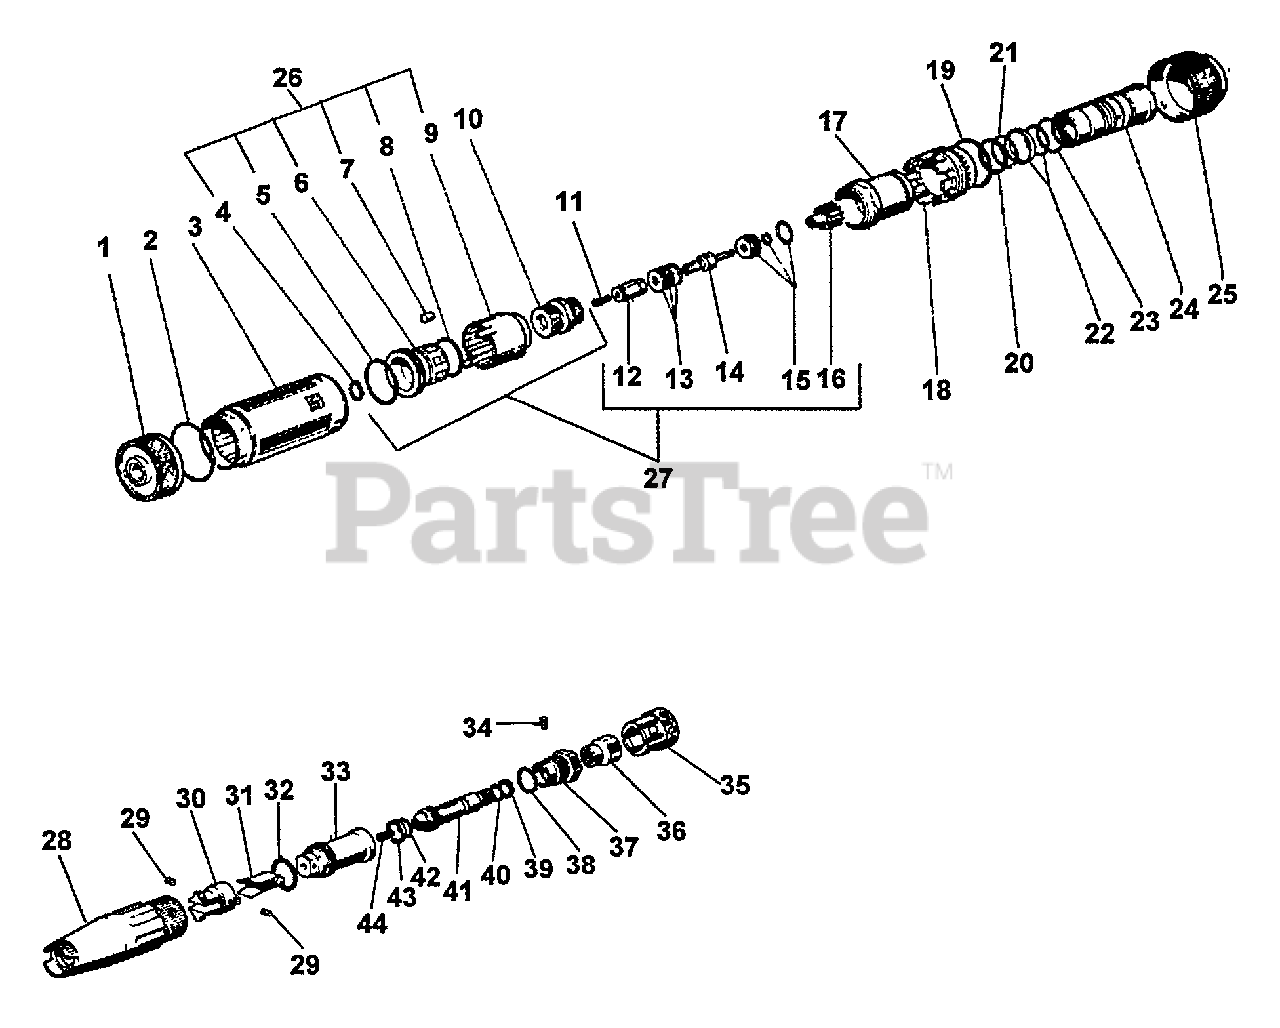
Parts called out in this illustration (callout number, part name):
1	CAP, FRONT
2	O-RING 33 05×1 78
3	KNOB
4	RING, SNAP
5	O-RING
6	ROTOR
7	BEARING, ROLLER
8	O-RING 0.797×.103
9	CLUTCH
10	NUT
11	NOZZLE - RED
12	HOLDER, NOZZLE
13	BEARING, BALL
14	CRANKSHAFT ASSY
15	SEAL
16	ROTOR
17	CYLINDER, DIFFUSER
18	DIFFUSER, LOW PRESSURE
19	O-RING 28 25×2 62
20	RING, ANTI-EXTRUSION
21	O-RING 20 35×1 78
22	SEAL
23	O-RING 18 72×2 62 VITON
24	BODY, DIFFUSER
25	RING, LOCKING
26	KIT, (PARTIAL) ROTOX REBUILD
27	KIT, (COMPL.) ROTOX REBUILD
28	KNOB, REGULATING
29	PIN
30	HOLDER, BLADE
32	O-RING 20 35×1 78
33	CYLINDER
34	PIN
35	KNOB, REGULATING
36	COUPLING
37	NUT, ADJUSTING
38	O-RING
39	RING, SEALING
40	O-RING 0.302×.070
41	TUBE
42	O-RING
43	SPACER
44	NOZZLE - RED
